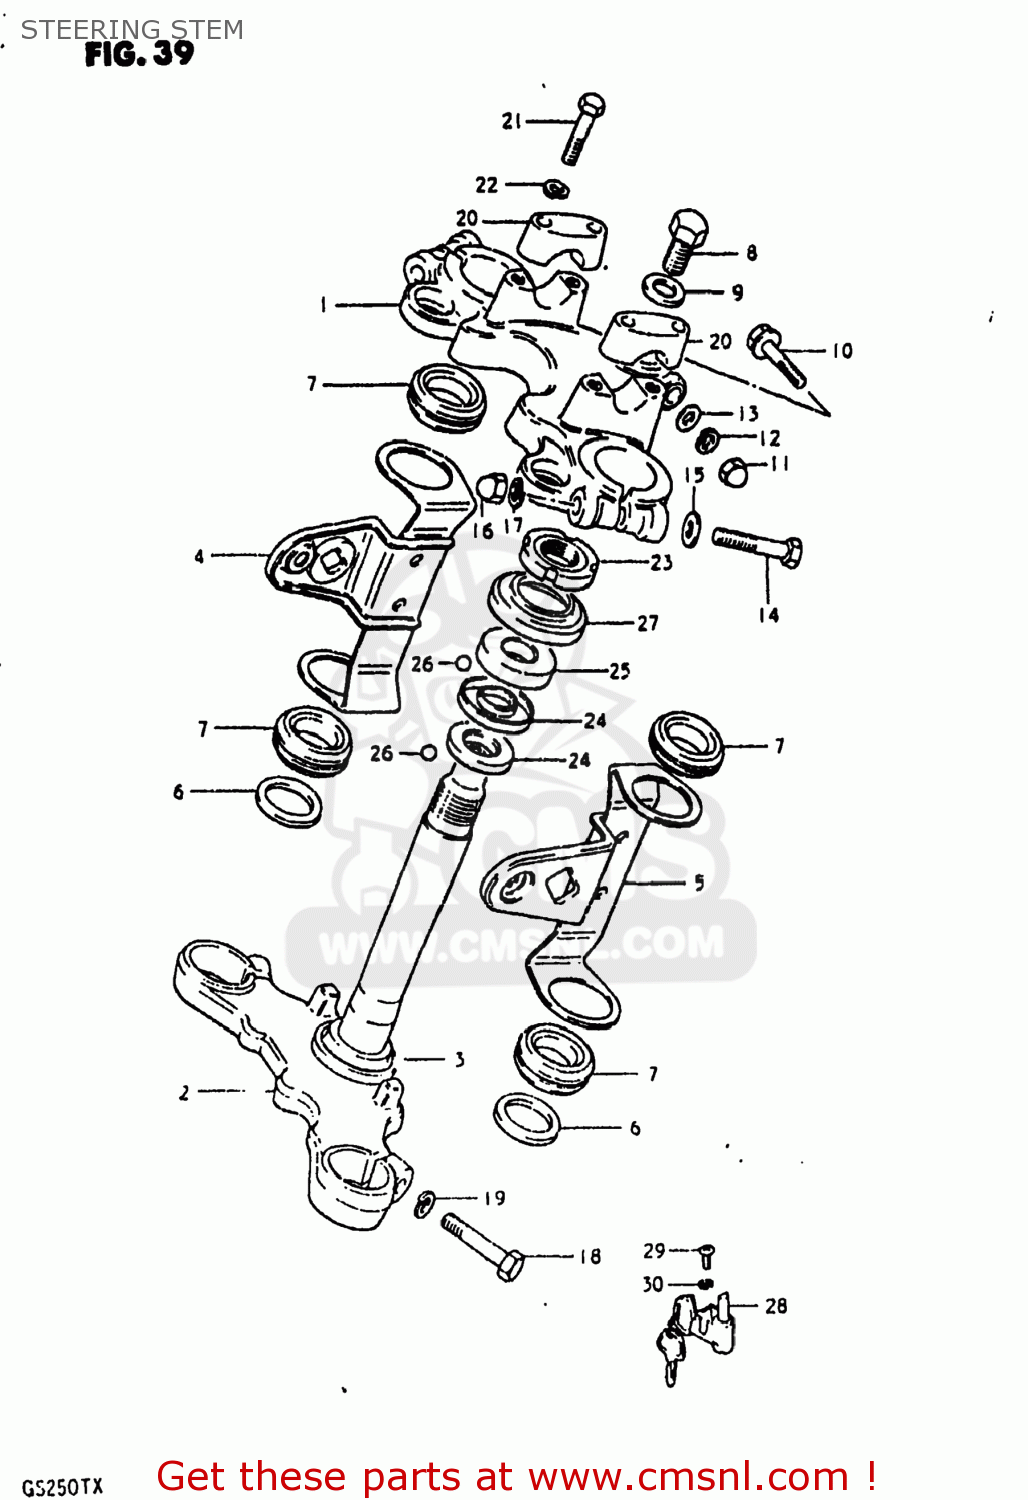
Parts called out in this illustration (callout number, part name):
1	HEAD,STEERING STEM
2	STEM,STEERING
3	RACE,STEERING OUTER LWR
4	BRACKET,HEADLAMP,RIGHT
5	BRACKET,HEADLAMP,LEFT
6	SEAT,HEADLAMP BRACKET LWR
7	CUSHION,HEADLAMP BRACKET
8	BOLT(12X20)
9	WASHER
10	BOLT
11	NUT
12	LOCK WASHER
13	WASHER
14	BOLT 10X55
15	WASHER
16	NUT
17	LOCK WASHER
18	BOLT 10X40
19	LOCK WASHER
20	HOLDER,HANDLE UPR
21	BOLT
22	LOCK WASHER
23	NUT,STEERING STEM(25X44X10)
24	LACE,STEERING INNER LWR
25	LACE,STEERING OUTER UPR
26	BALL
27	DUST SEAL,STEERING UPR
28	LOCK ASSEMBLY,STEERING
29	SCREW
30	LOCK WASHER
